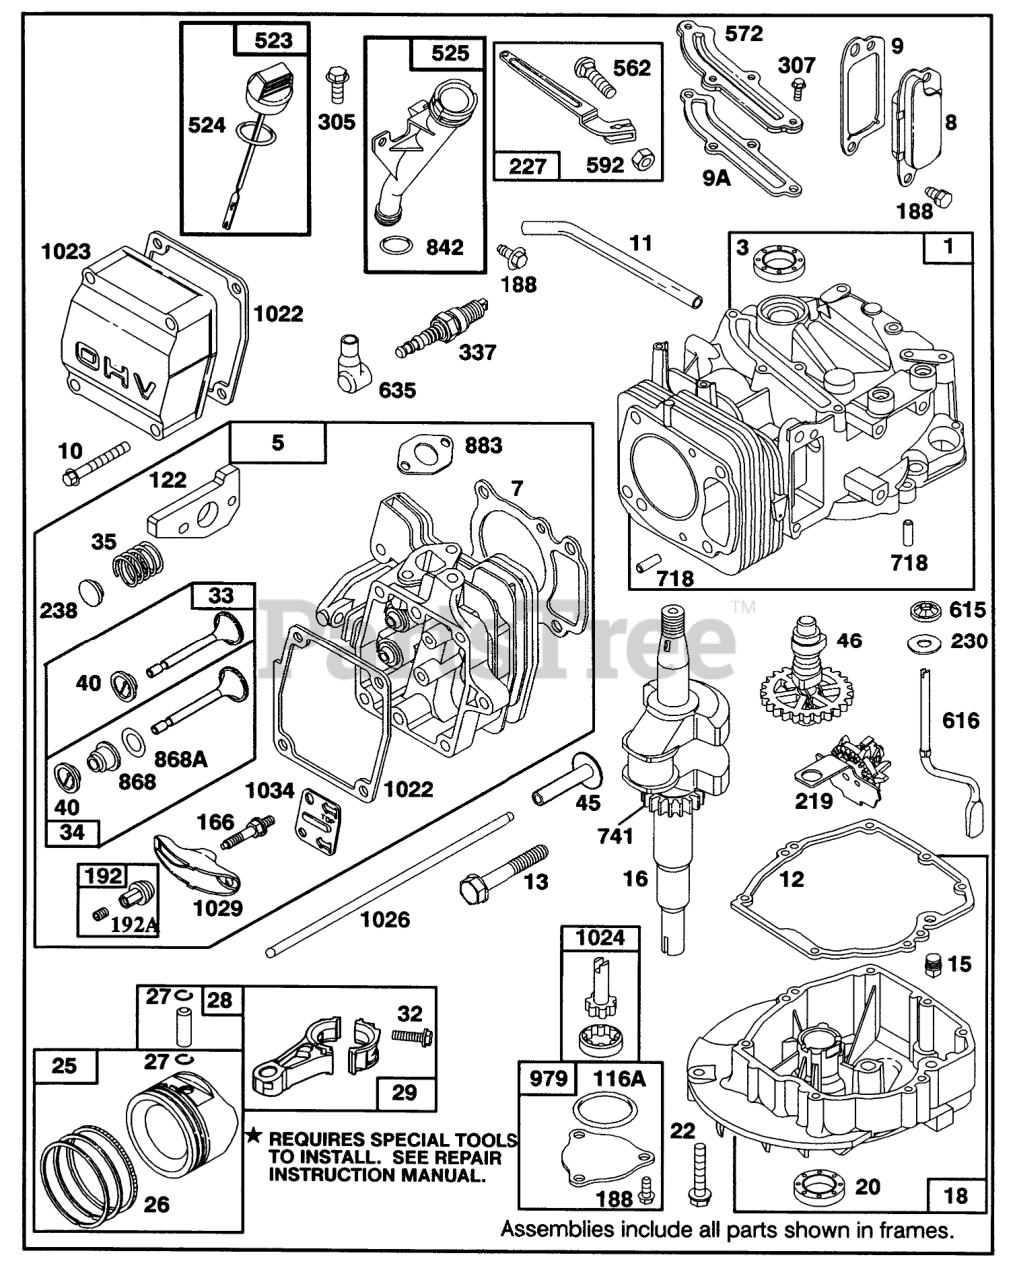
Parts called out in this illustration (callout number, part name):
1	CYLINDER ASSEMBLY
3	SEAL - OIL
5	CYLINDER HEAD
7	CYLINDER HEAD GASKET
8	Breather Assy
9	Gasket-Breather
9A	GASKET-BREATHER
10	HEX HEAD SCREW
11	BREATHER TUBE
12	ENGINE BASE GASKET
13	CYLINDER HEAD SCREW
15	PLUG - OIL DRAIN
16	CRANKSHAFT
18	ENGINE SUMP
20	SEAL-OIL
22	SCREW - ENGINE BASE
25	STD PISTON ASSEMBLY
26	STD RING SET
27	PISTON PIN LOCK
28	Pin Assy-Piston
29	CONNECTING ROD
32	Connecting Rod
33	EXHAUST VALVE
34	INTAKE VALVE
35	VALVE SPRING
40	SPRING RETAINER
45	VALVE TAPPET
46	CAM GEAR
116A	O RING SEAL
122	ADAPTER ASSEMBLY
166	ROCKER ARM STUD
188	SCREW - SEM
192	NUT - HEX SPECIAL
192A	Screw-Set
219	GOVERNOR/OIL SLINGER
227	GOVERNOR LEVER ASSEMBLY
230	WASHER
238	VALVE CAP
305	SCREW - HEX HEAD
307	SCREW - SEM
337	PLUG-SPARK
523	DIPSTICK-OIL
524	O-RING
525	OIL FILLER TUBE
562	GOVERNOR LEVER BOLT
572	BAFFLE - CYCLINDER
592	HEX NUT
615	FASTENER
616	GOVERNOR CRANK
635	SPARK PLUG ELBOW
718	DOWEL - SLEEVE
741	TIMING GEAR
842	O-RING
868	SealAssy-Valve
868A	Seal-Valve
883	EXHAUST GASKET
979	OIL PUMP COVER
1022	ROCKER COVER GASKET
1023	Cover-Valve
1024	OIL PUMP
1026	PUSH ROD
1029	ROCKER ARM
1034	PUSH ROD GUIDE
